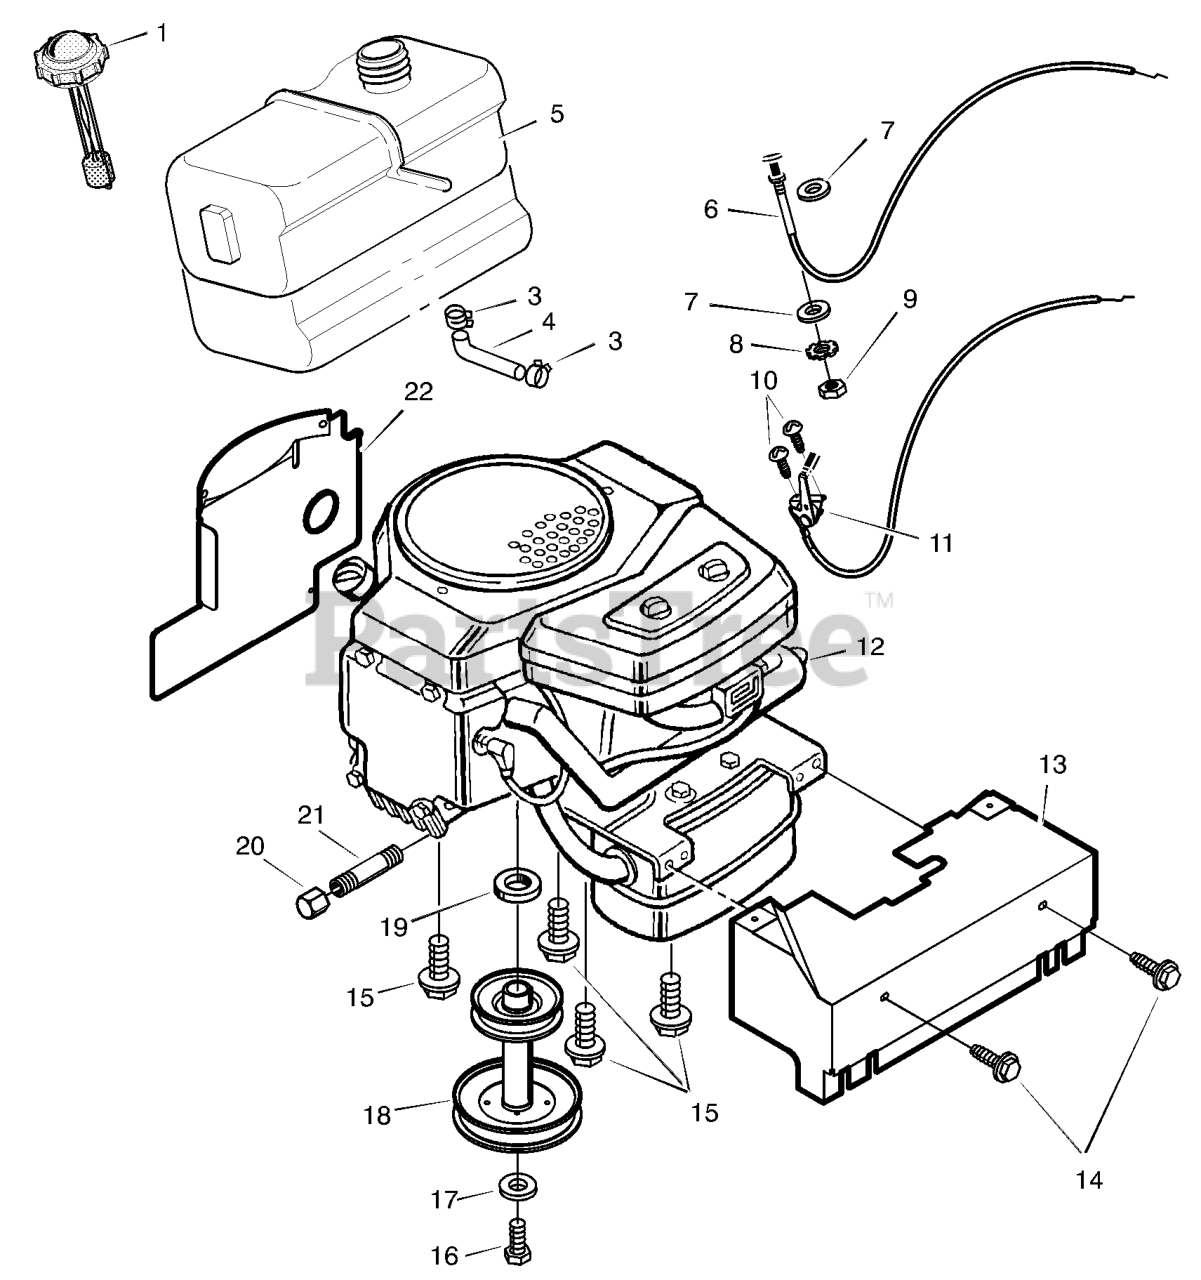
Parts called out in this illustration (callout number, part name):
1	Cap, Gas
3	Clamp
4	Line, Fuel
5	Tank, Fuel
6	Cable, Choke
7	Washer
8	Lockwasher
11	Control, Throttle
12	Engine *
13	Shield Assembly, Heat
15	Screw
18	Pulley, Stack
20	Cap, Oil Drain
21	Pipe, Oil Drain
22	Baffle, Rear Heat
